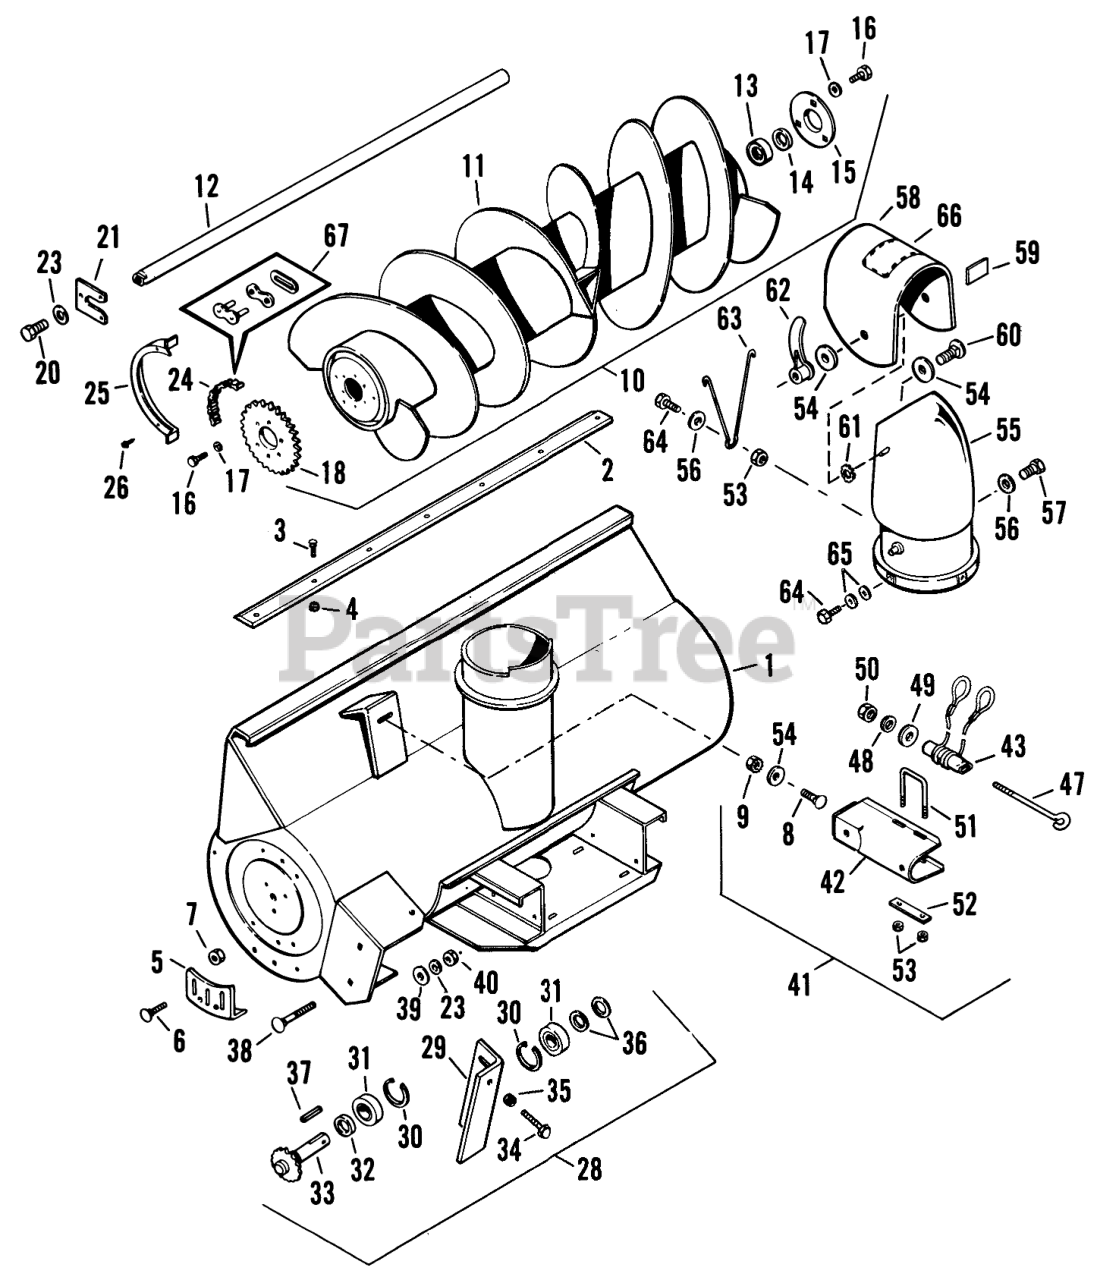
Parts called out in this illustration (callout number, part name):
1	Assy.-Header Hsg. 48"
2	Blade-Scraper
3	BOLT-BLADE TO HEADER
4	Nut 1/4-20 Keps
5	Shoe-Skid
6	Bolt-5/16-18 x 3/4 Carr.
7	Nut 5/16-18 Keps
8	Bolt 3/8-16 x 1
9	Nut, Jam, 3/8-24 Thd
10	Auger Assembly
11	Auger
12	Hex Nut
13	Bearing-Auger
14	Washer-Auger
15	Spring
16	Bolt Hex 5/16-18
17	Lockwasher
18	Control Rod-Traction
20	Bolt Hex 1/2-13 x 1 1/4
21	PLATE AUGER MOUNTING
23	Lockwasher
24	CHAIN-AUGER DRIVE
25	Chain Guard
26	Screw-1/4-14 x 1/2 Hex. Self Tap
28	Jackshaft Housing w/Bearings
29	Assy.-Jackshaft Hsg.
30	Ring-Snap
31	BEARING-GEAR BOX
32	Spacer
33	Jackshaft and Sprocket
34	S.T. Bolt 5/16-18 x 2
35	Nut 5/16-18 Jam
36	WSHR SPROCKET TO BRG
38	Bolt-1/2-13 x 3-1/2 Carr.
39	Washer 7/16
40	Nut, 1/2-13
41	Stack Drive Bracket
42	Assy.-Stack Drive Brkt.
43	ASSEMBLY CABLE
47	EYE BOLT DRIVE TUBE
48	Spring Washer
49	Washer
50	3/8-16 E.S.
51	U-BOLT
52	Friction Strap
54	WASHER
55	Assy.-Elbow & Pivot
56	Washer
57	Bolt, 1/4-x 1/2
58	Deflector Elbow
59	MOLDING DEFLECTOR
60	Bolt-Car. 5/16-18 x 1
61	Washer
62	STRAP-LOCKING
63	Spring Hook
64	Bolt-1/4-20 x 5/8
65	Washer-1/4 Med. Lock
